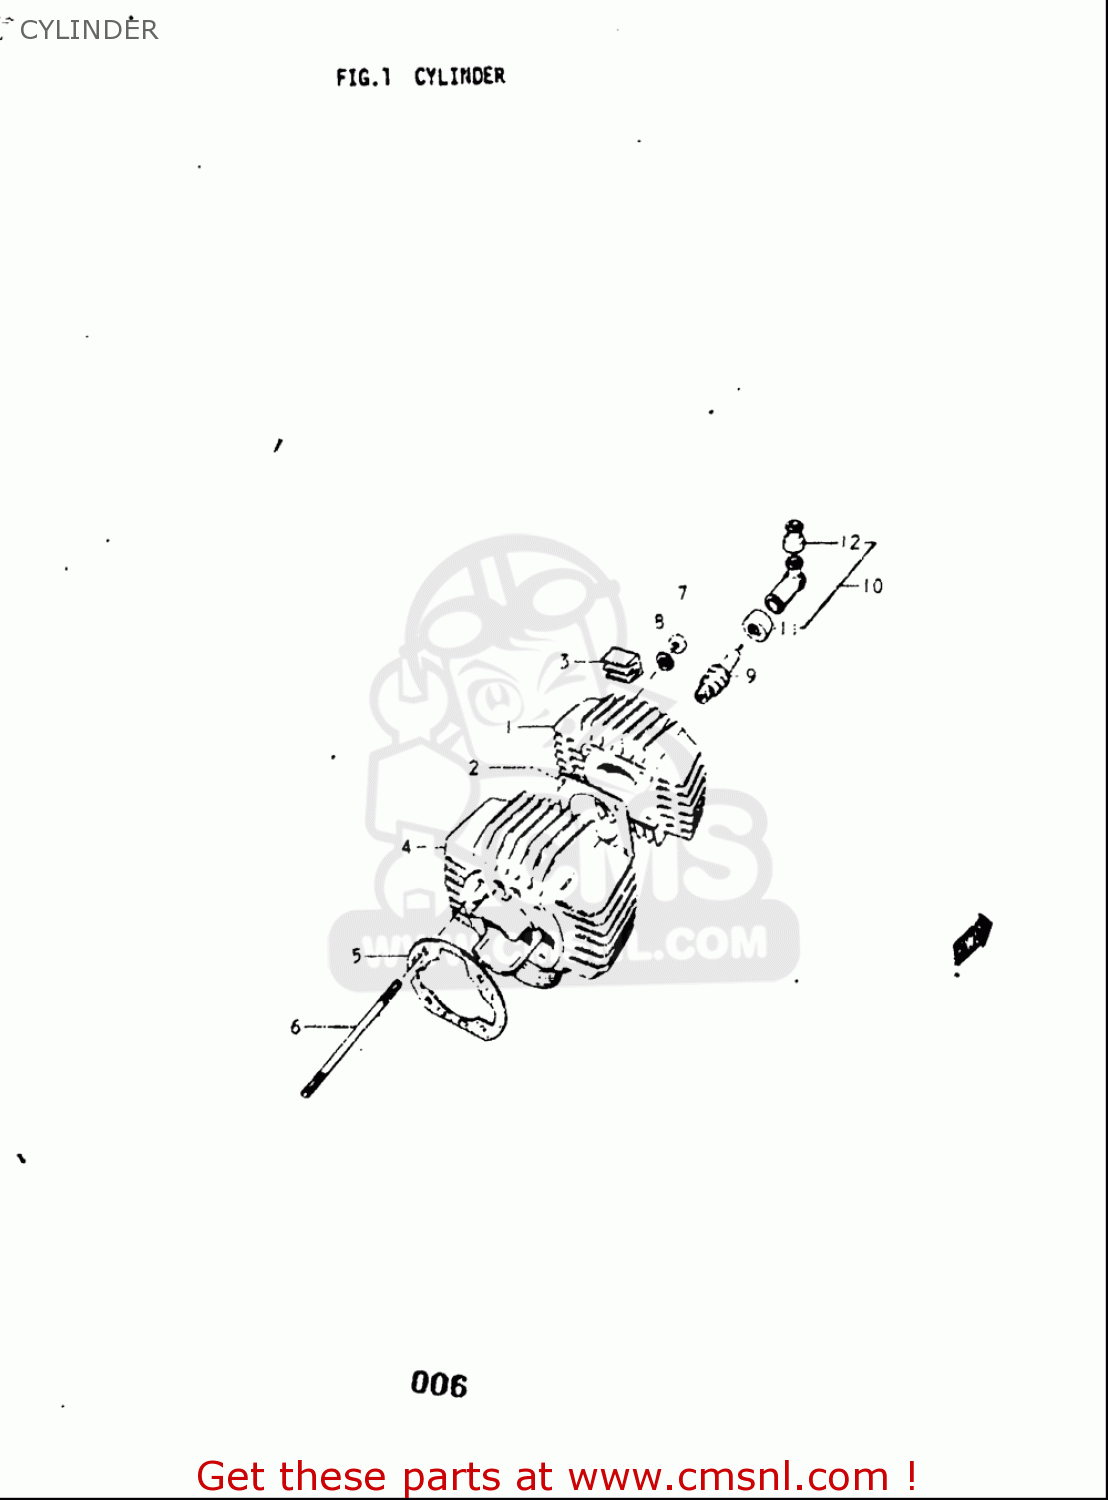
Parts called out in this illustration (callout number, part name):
1	HEAD,CYLINDER
2	GASKET,CYLINDER HEAD (NAS)
3	PAD,CYLINDER
5	GASKET,CYLINDER
6	BOLT,STUD
7	NUT
8	WASHER,LOCK
9	PLUG,SPARK(BP7HS)
10	CAP,SPARK PLUG
11	SEAL,SPARK PLUG
12	SEAL,HIGH TENSION CORD
